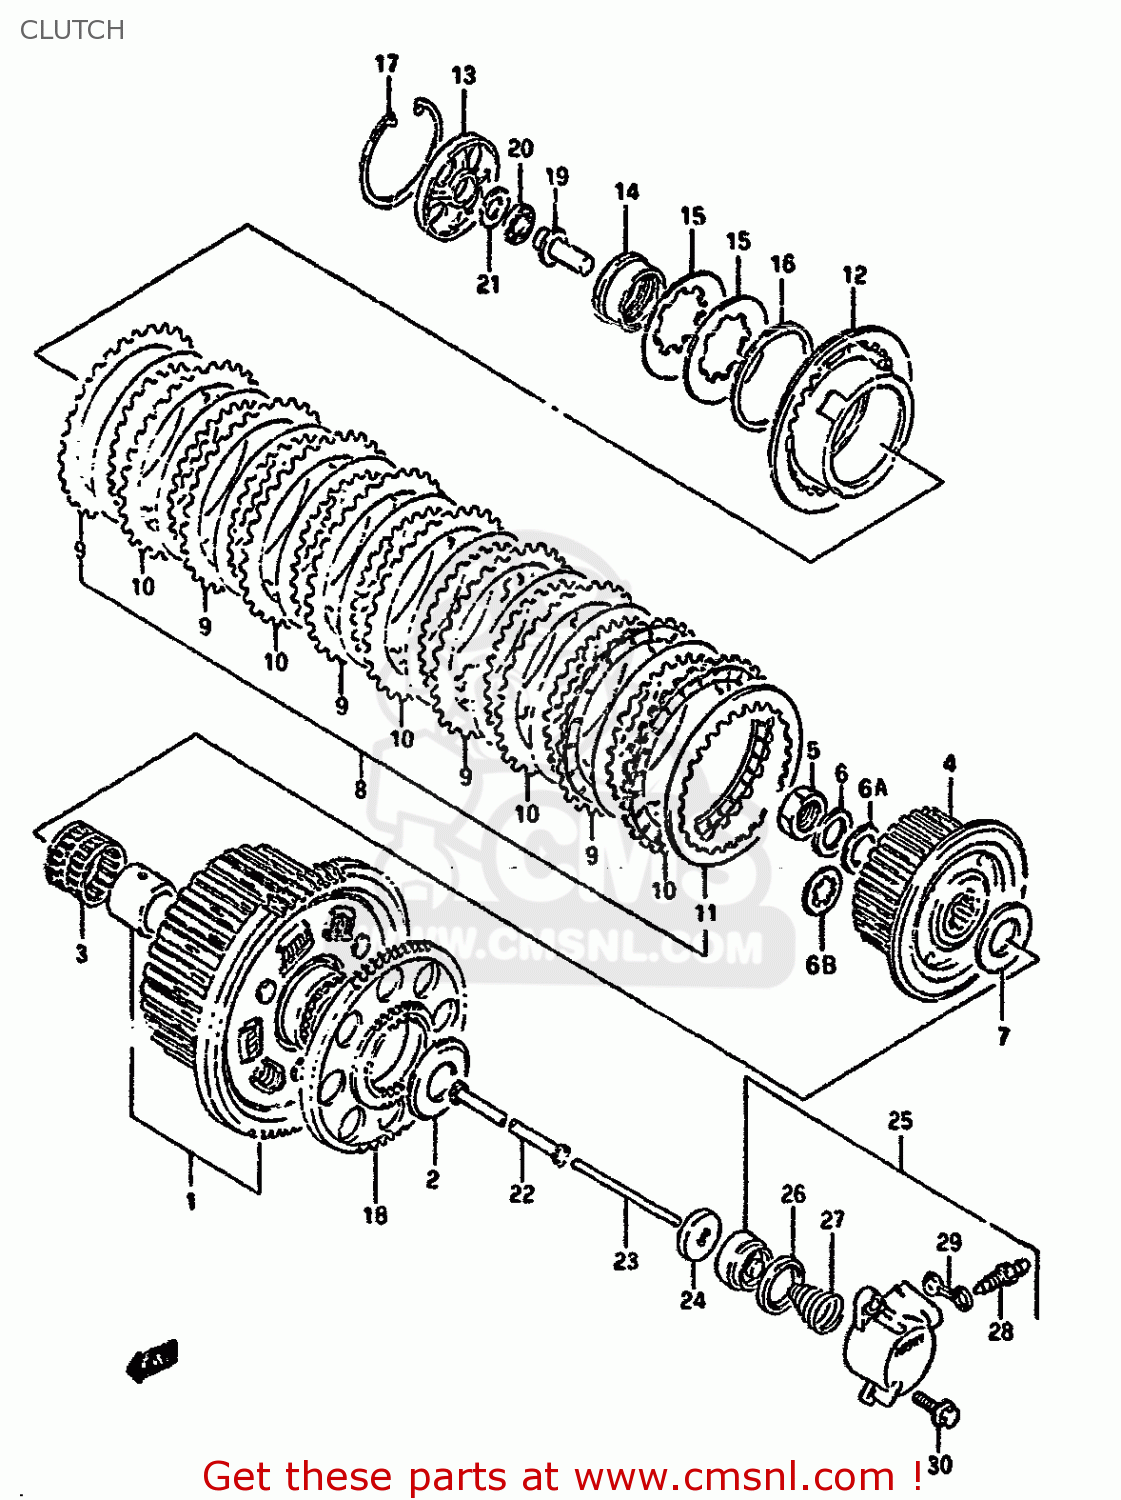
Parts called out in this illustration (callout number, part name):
1	GEAR ASSEMBLY,PRIMARY DRIVE
2	WASHER(25X54X2.5)
3	BEARING(35X40X35.8)
4	HUB,CLUTCH SLEEVE
5	NUT
6	WASHER
6A	SHIM
6B	WASHER,LOCK
7	WASHER(25X50X2.5)
8	PLATE ASSY,CLUTCH
9	PLATE,CLUTCH DRIVE (NAS)
10	PLATE,CLUTCH DRIVE NO.1 (NAS)
11	PLATE,CLUTCH DRIVEN (NAS)
12	DISC,CLUTCH PRESSURE
13	LIFTER,CLUTCH PRESSURE DISC
14	HOLDER,CLUTCH SPRING
15	WASHER
16	SEAT,CLUTCH SPRING
17	CIRCLIP
18	GEAR,GENERATOR DRIVE
19	PIECE,CLUTCH PUSH
20	BEARING(15X28X2)
21	WASHER(15.5X28X1)
22	ROD,CLUTCH PUSH,R
23	ROD,CLUTCH PUSH,L
24	SEAL,OIL(6X34X5.5)
25	CYLINDER,CLUTCH RELEASE
26	CUP
27	SPRING,CLUTCH CYLINDER
28	BLEEDER
29	CAP,BLEEDER
30	BOLT
